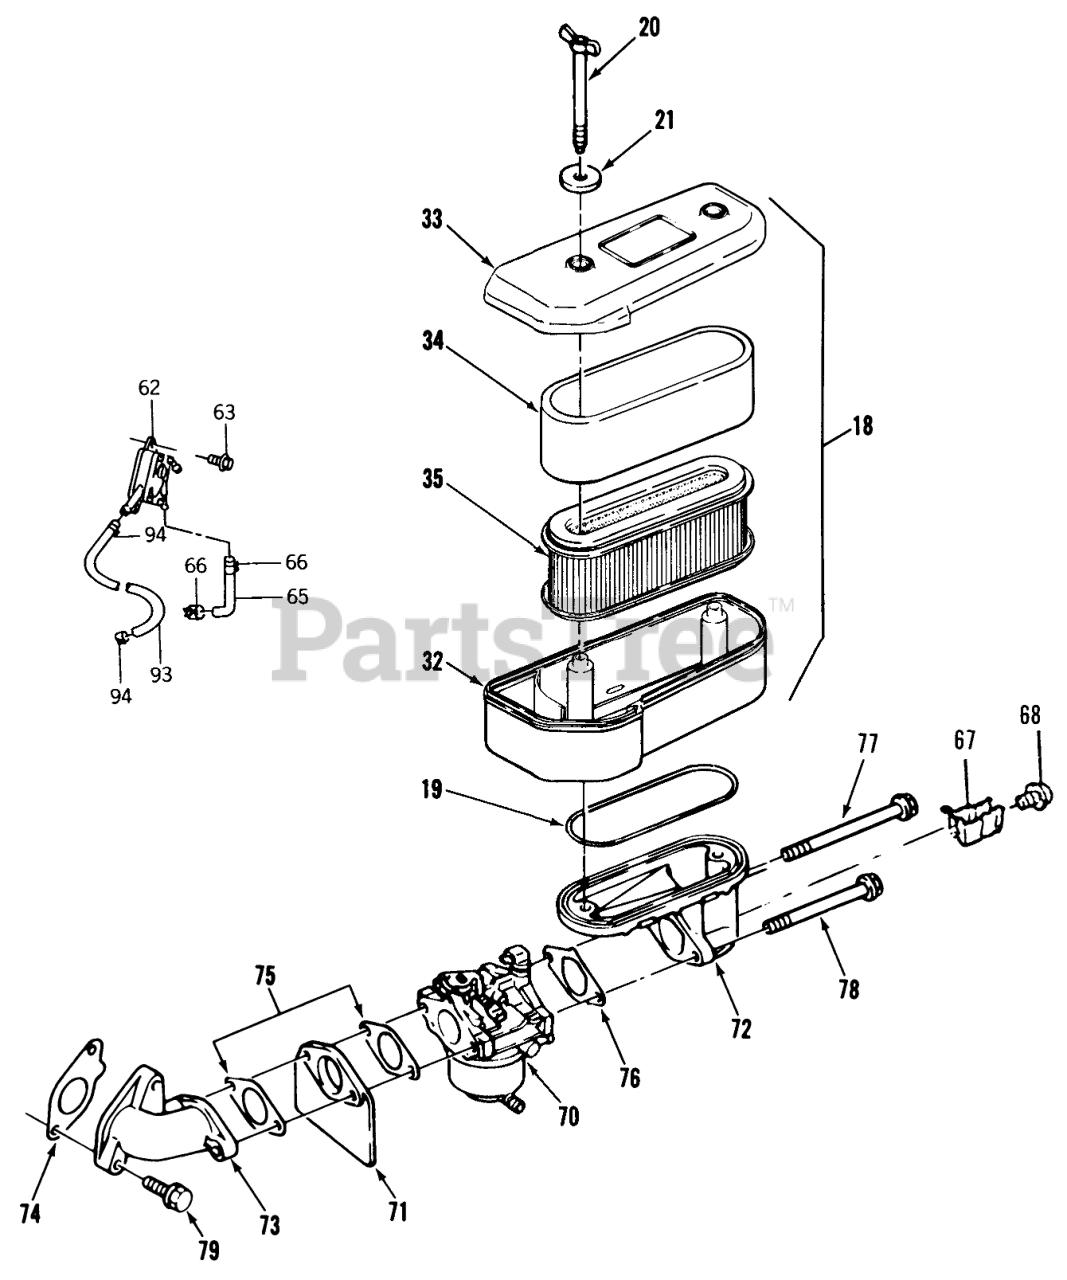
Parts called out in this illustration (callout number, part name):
18	11010-2291 Air Filter Assy (includes items 32, 33, 34 & 35)
19	GASKET
21	WASHER
32	CASE-AIR FILTER
33	CAP-AIR FILTER
34	ELEMENT-AIR CLEANER
35	AIR CLEANER ELEMENT
62	Fuel Pump Assy-See Section 9-8 for complete parts breakdown
63	BOLT-FLANGED
67	CLAMP
68	Screw 5 x 8
70	Carburetor Assy See section 9-6 for complete parts breakdown
71	INSULATOR
72	MANIFOLD INTAKE
73	MANIFOLD INTAKE
74	GASKET
75	GASKET
76	GASKET
79	BOLT, FLANGED 8X25
